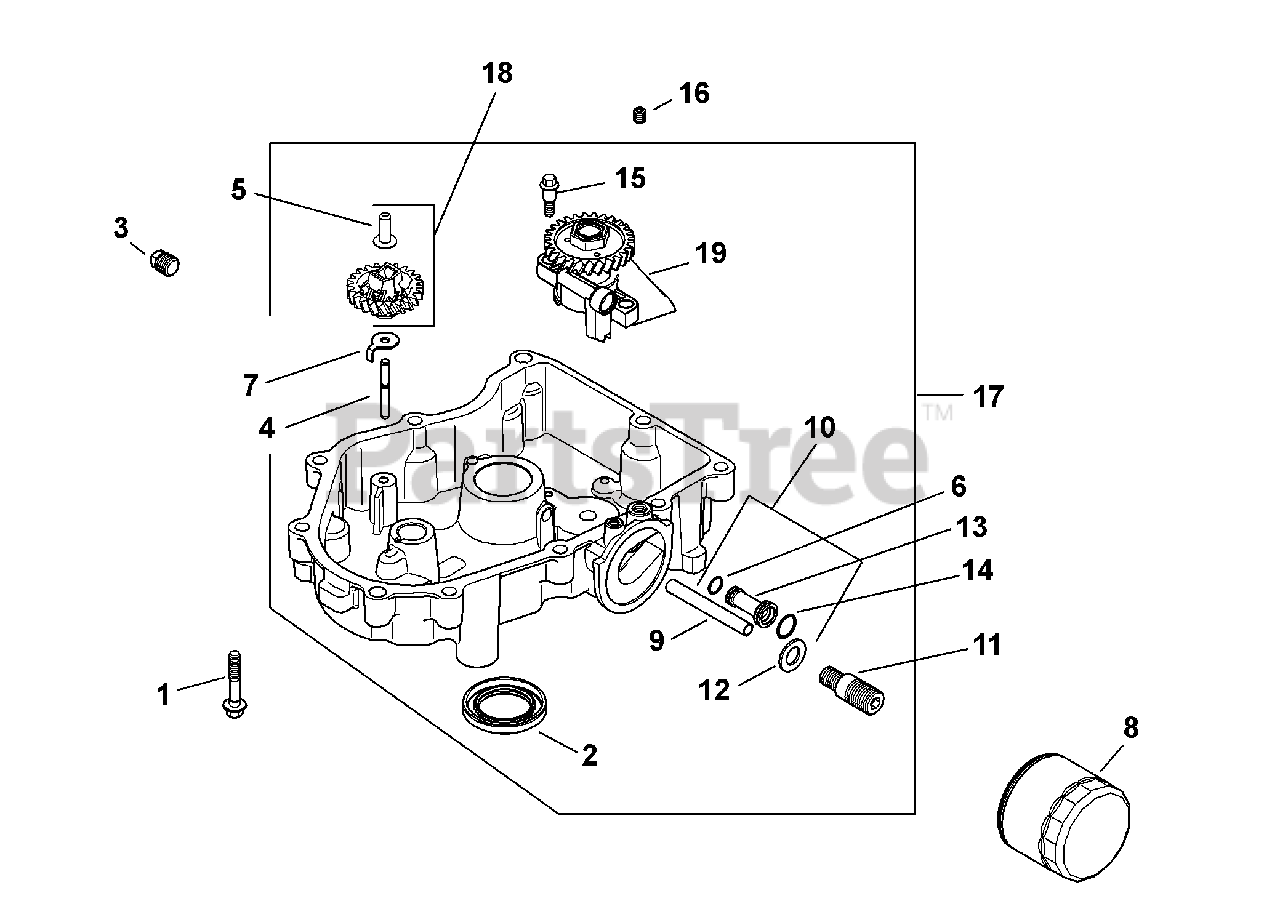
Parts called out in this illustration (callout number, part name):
1	Flange Screw, M8 x 1.25 x 45
2	Oil Seal, 2.38 x 1.45
3	Square Head Pipe Plug, 3/8
4	Governor Gear Shaft
5	Governor Regulating Pin
6	Oil Pick-Up O-Ring
9	Oil Feed Tube (Filter to Pan)
10	Oil Feed Tube Assembly
11	Oil Filter Nipple
13	Oil Feed Tube
15	Screw, M6 x 6.5
16	Pipe Plug, 1/8
